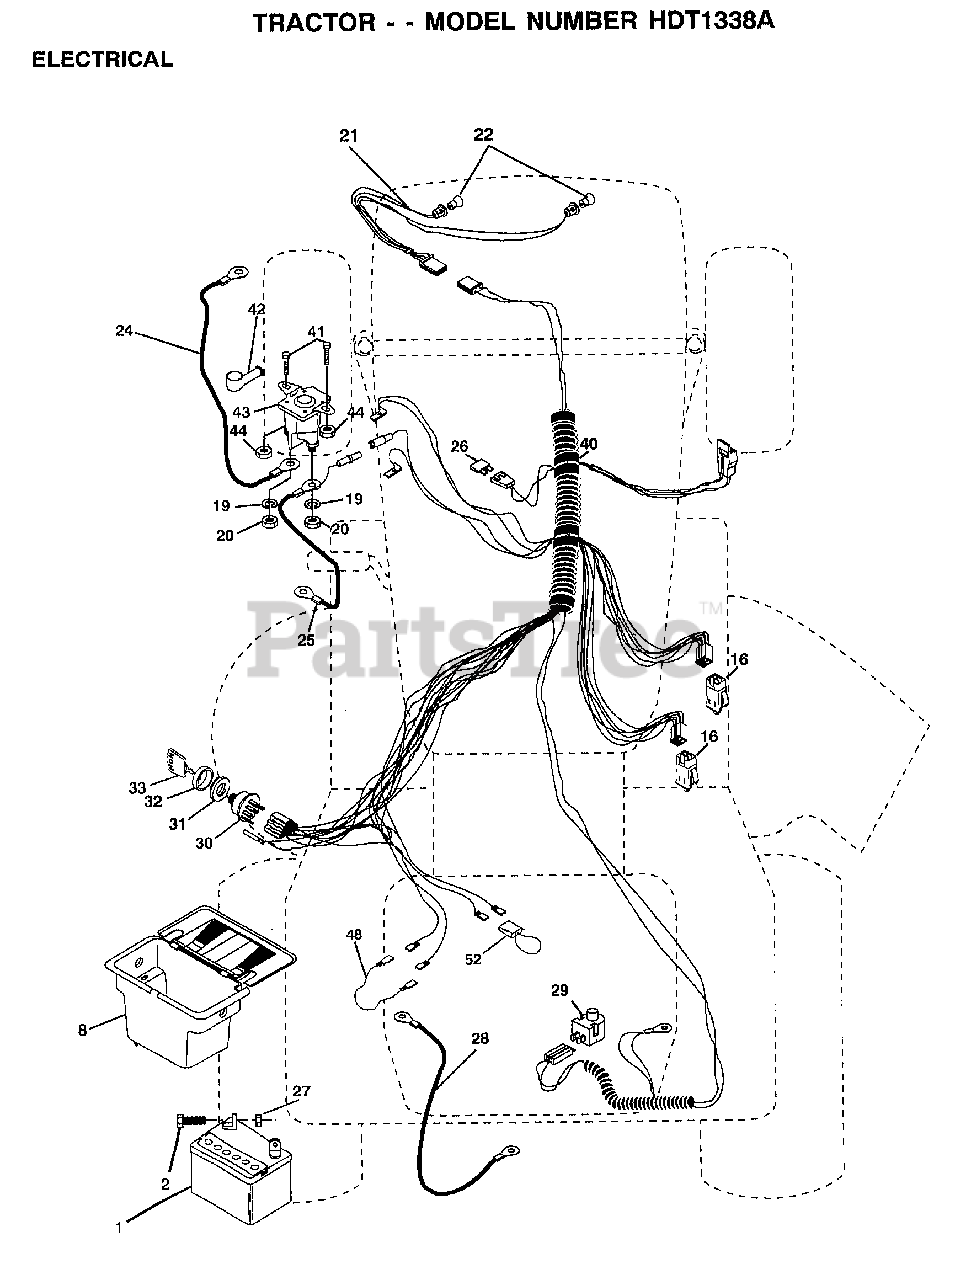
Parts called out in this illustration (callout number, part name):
2	BOLT LT
8	"CASE,BATTERY.MECH"
16	SWITCH INTERLOCK
20	NUT
21	HARNESS.ASM.LIGHT W/4152J
22	HEADLAMP BULB
24	CABLE ASM.
25	CABLE.BTRY.6GA.RD
26	FUSE.15 AMP
27	NUT
28	CABLE T
29	SWITCH SEAT
30	SWITCH IGN 4POS
31	NUT IGNITION
32	COVER KEY SWITCH
33	KEY
40	HARNESS.IGNITION
41	BOLT HXHD FIN
44	NUT HXKEP 1/4X20
48	ADAPTER AMMETER
52	PROTECTION LOOP
